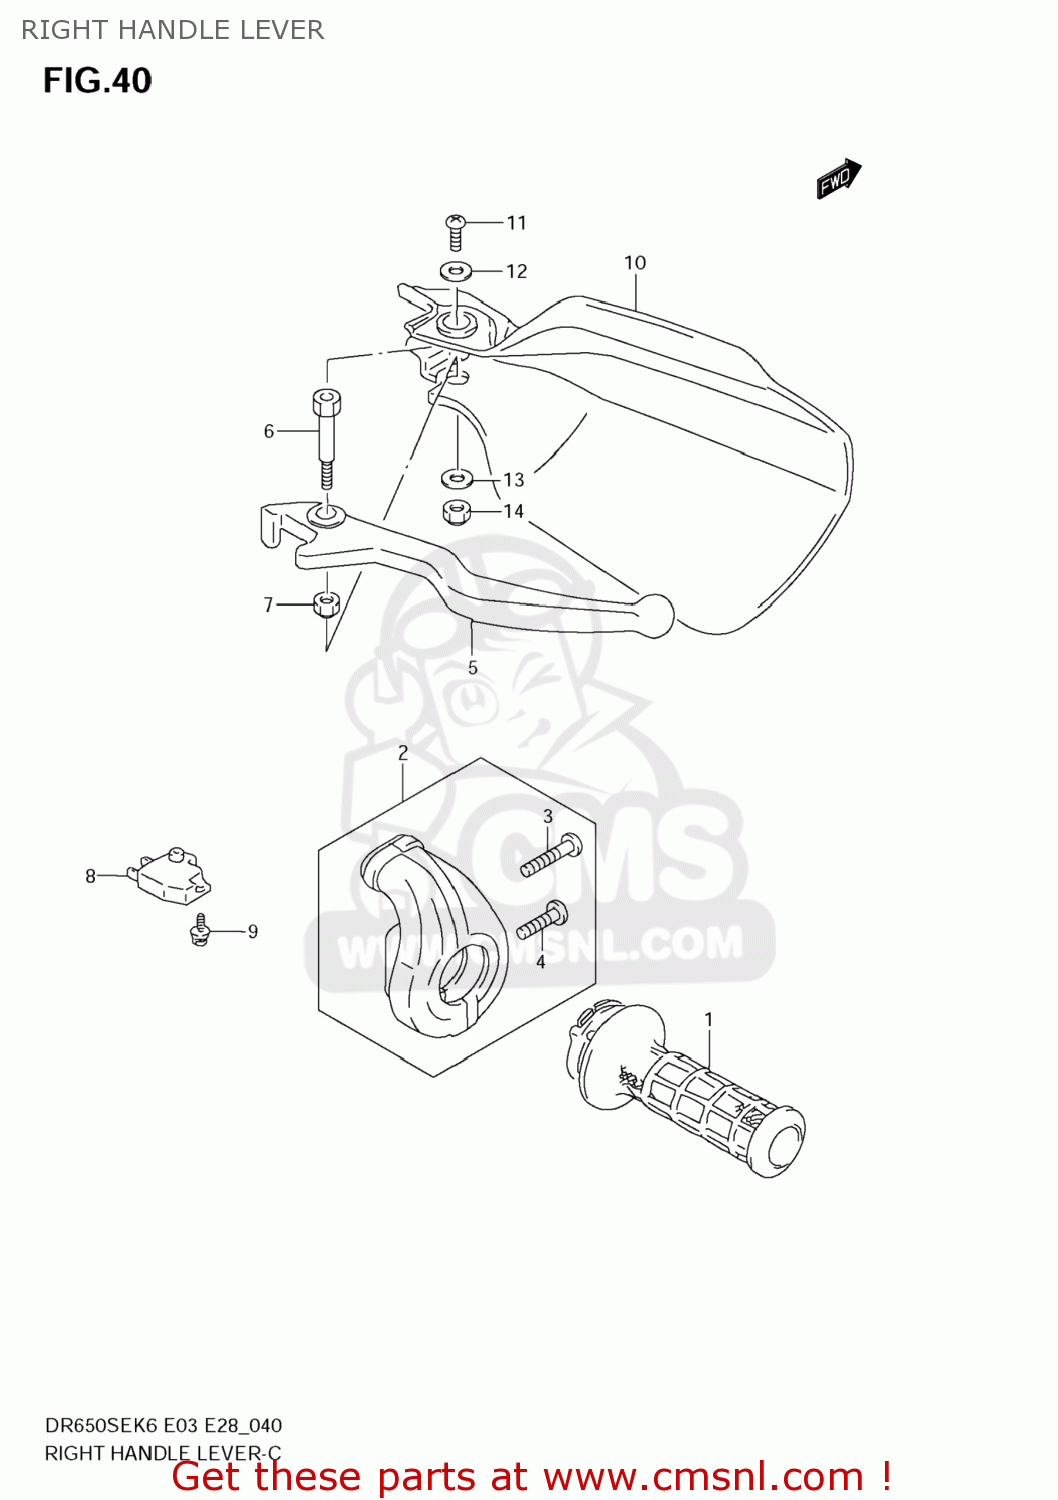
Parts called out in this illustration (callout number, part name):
1	GRIP,THROTTLE
2	CASE ASSY,THROTTLE
3	SCREW(5X25)
4	SCREW 5X20
5	LEVER,BRAKE
6	BOLT,BRAKE LEVER PIVOT
7	NUT,LEVER PIVOT
8	SWITCH ASSY,ST
9	SCREW
10	COVER,KNUCKLE,R
11	SCREW
12	WASHER(5.5X16X1.2)
13	WASHER(6.5X16X1.6)
14	NUT
